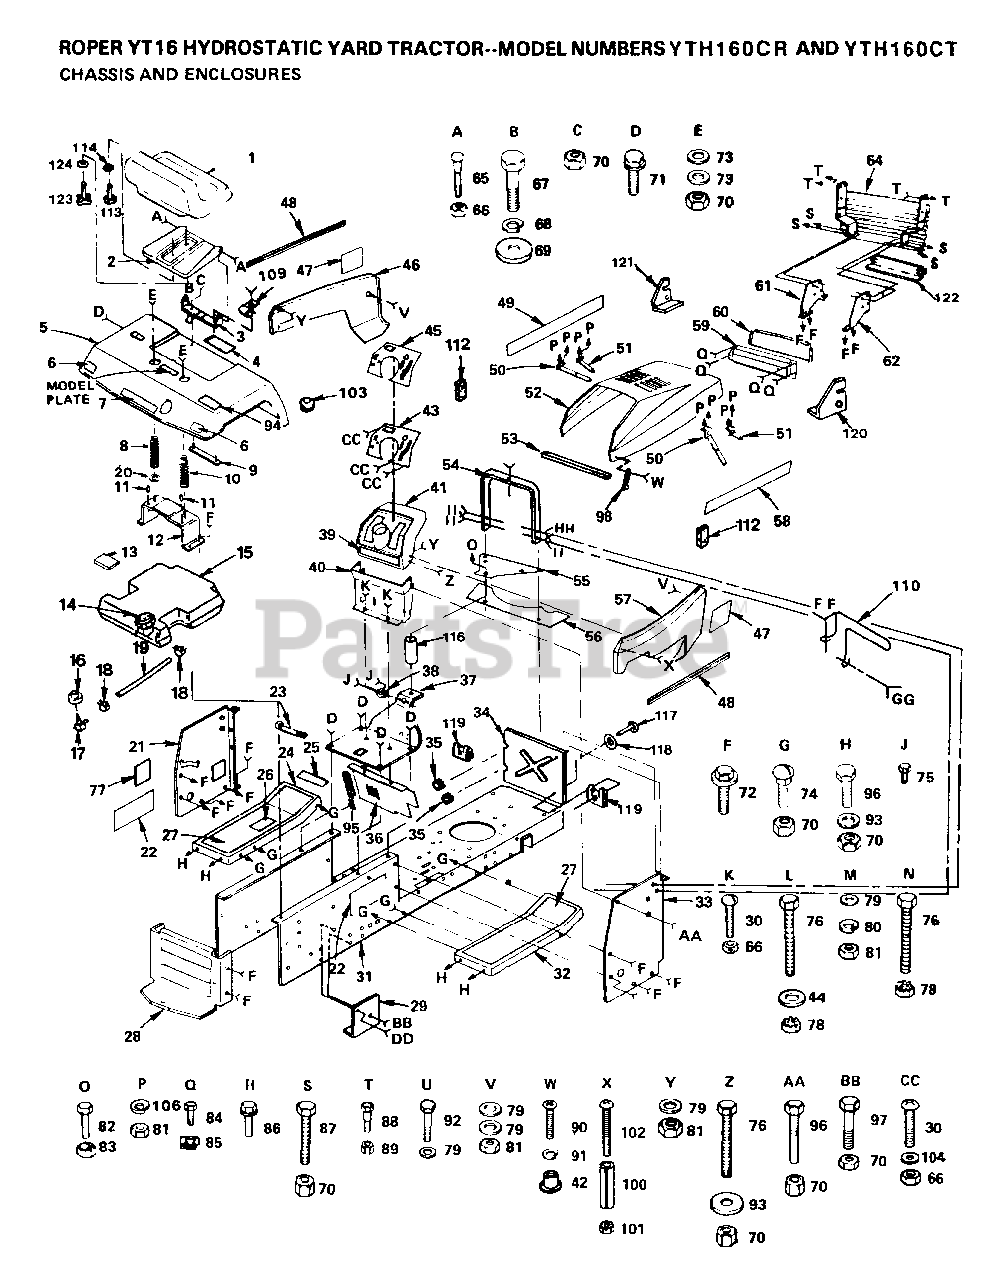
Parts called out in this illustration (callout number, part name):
6	REFLECTOR-TAIL YT
11	NUT-PUSH YT
13	PAD-SPACER T
15	TANK.FUEL.LT.
16	BUSHING OUTLET T
17	FUEL TANK STEM GT
20	SPACER WASHER YTH
21	DASH PANEL T
25	DECAL T
29	DEFLECTOR HYT
30	SCREW
40	LOWER DASH
42	WELDNUT
43	PLATE - DASH
44	WASHER
45	DECAL - DASH
47	DECAL-SIDE PANEL
49	No Desciption for Part
53	FOAM-STRIP LT
60	LENS LT
61	SUPPORT LH YTH
62	SUPPORT RH YTH
68	LOCKWASHER
69	WASHER T
71	SCREW LT
72	SCREW
73	WASHER
74	BOLT
78	NUT
79	WASHER PM
80	LOCKWASHER
82	BOLT
85	"""J"" FASTENER LT"
86	SCREW
87	BOLT
88	BOLT T
90	SCREW
91	LOCKWASHER
92	SCREW HEX CRT
93	WASHER
94	DECAL-CAUTION
95	FOAM STRIP HYT
100	SPACER LT
101	WASHER
102	SCREW
103	GROMMET T
104	WASHER
109	CLIP T
110	GUARD MUFFLER HYT
112	STRIP - FOAM
114	No Desciption for Part
116	SPACER-SPLIT YTV
118	RETAINER LT
119	RECEPTACLE LT
120	SUPPORT RH YTH
121	SUPPORT LH YTH
123	"KNOB 1/2"" YT"
